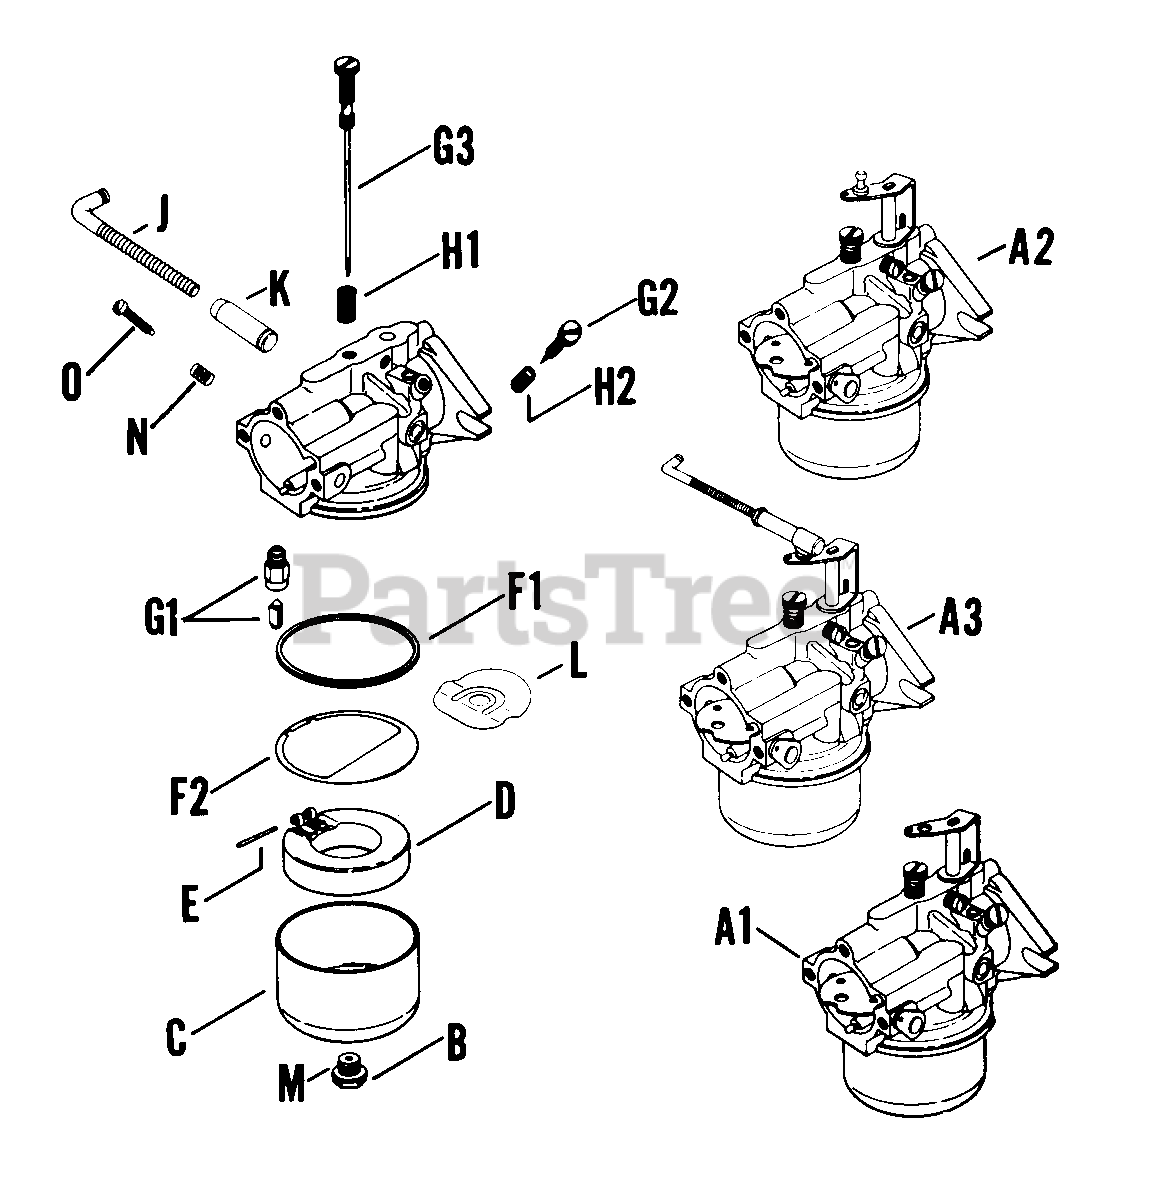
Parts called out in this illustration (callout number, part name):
A1	CARBURETOR - USE 47 053 14
B	NUT - USE 47 100 04
D	KIT, FLOAT REPAIR - DISCONTINUED
G1	Needle and seat
G2	SCREW - DISCONTINUED
H2	SPRING - DISCONTINUED
O	KIT - USE 25 757 01
